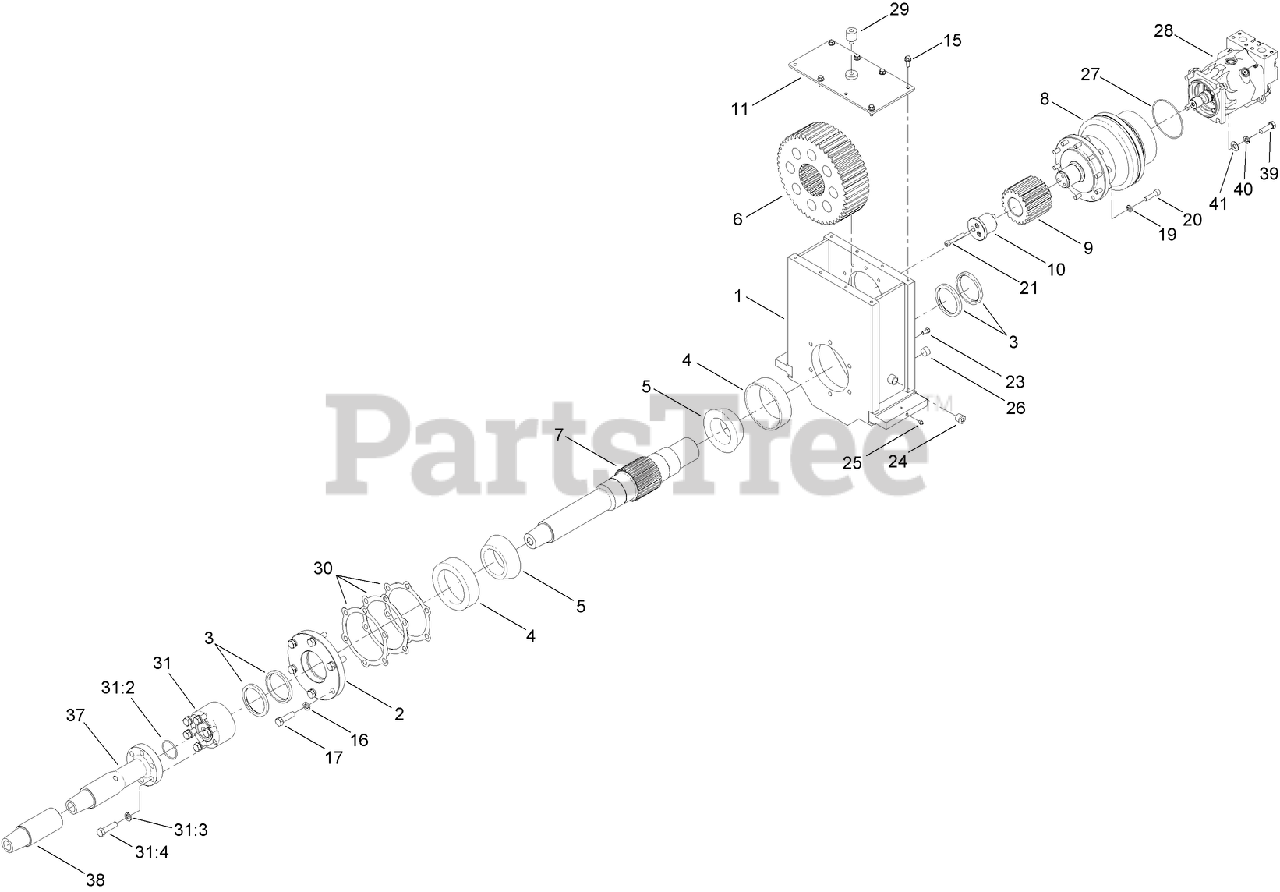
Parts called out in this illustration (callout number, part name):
1	BOX-ROTARY
2	CAP-BEARING, ROTARY
3	SEAL-SHAFT
4	CUP-BEARING
5	CONE-BEARING
6	GEAR-RING, ROTARY
7	SPINDLE-ROTARY
8	PLANETARY GEARBOX ASM
9	PINION-ROTARY
10	CAP-PINION, ROTARY
11	COVER-BOX, ROTARY
15	SCREW-HHF
16	WASHER-LOCK/SP
17	SCREW-HH
19	WASHER-LOCK
20	SCREW-HSFH
21	SCREW-HSH
23	SCREW-HH
24	PLUG-SITE, GLASS
25	FITTING-GREASE
26	PLUG-MAGNETIC, HEX
27	O-RING
28	HYD MOTOR ASM
29	BREATHER
30	SHIM-BEARING ADJUST (.020)
30	SHIM-BEARING ADJUST (.007)
30	SHIM-BEARING ADJUST (.005)
31	SPINDLE ASM
31:2	O-RING
31:3	WASHER-LOCK
31:4	SCREW-HH
37	ADAPTER-FLANGE
38	SAVER ASM
39	SCREW-HH
41	WASHER
